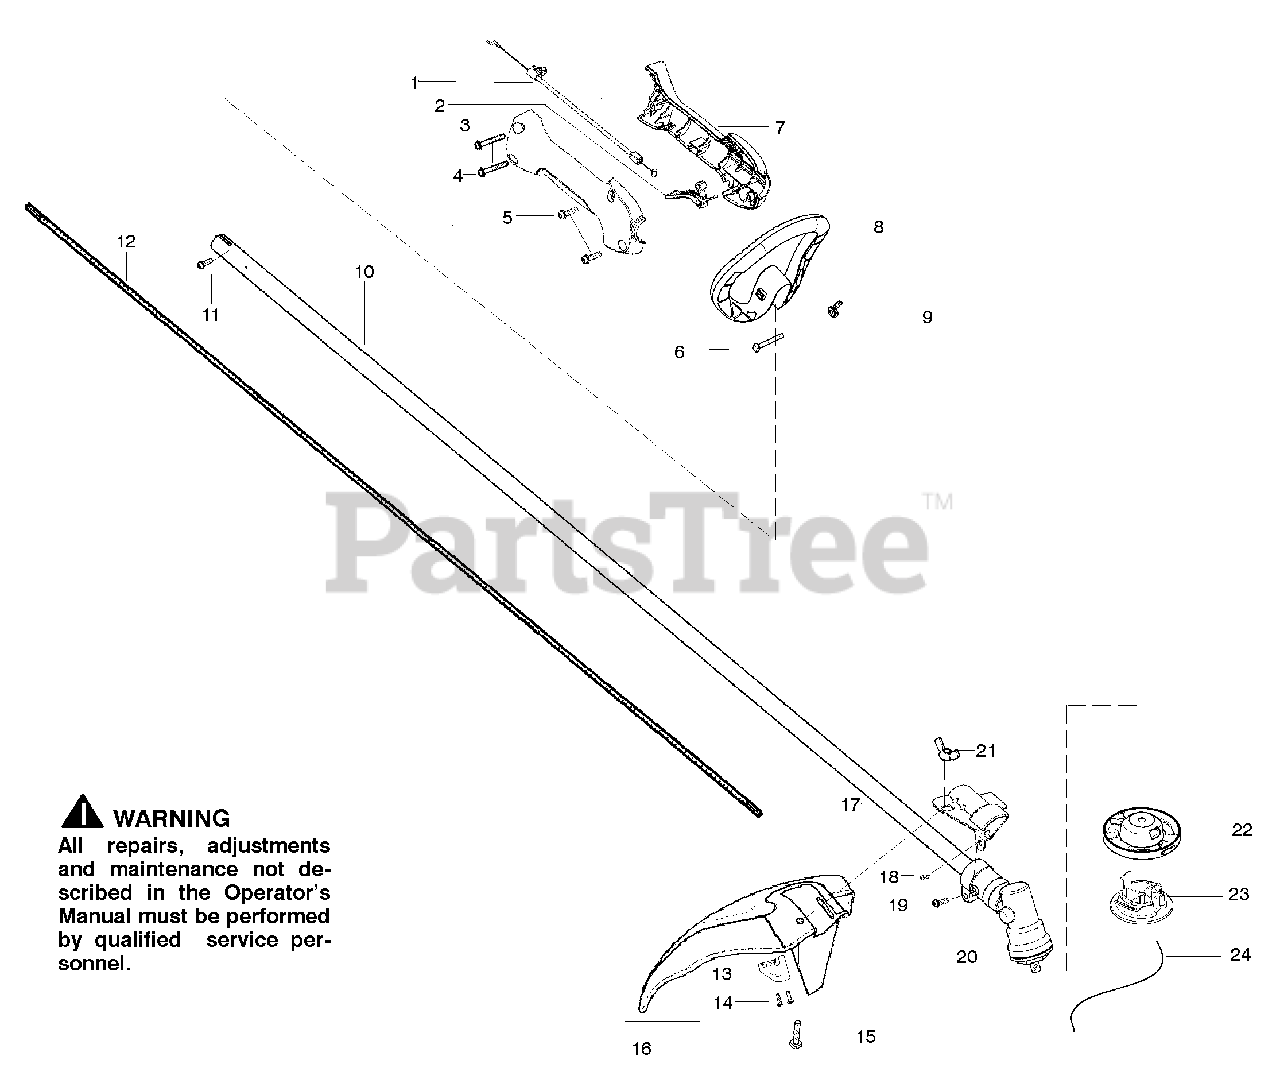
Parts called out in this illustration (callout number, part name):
1	Assy-Throttle Cable
3	Throttle Hsg. (Right)
6	Bolt-Handle
7	Throttle Hsg. (Left)
8	Assy-Handle
9	Wingnut-Handle
10	Assy-Drive Shaft Hsg.
11	Screw
12	Shaft- Flex
13	Line Limiter
15	Bolt-Shield
16	Kit-Shield Assy
17	Bracket-Shield
20	Assy-Gearbox
21	Wingnut
22	Head- Fixed Line
23	Cap- Fixed line
24	Line .095 round (5 pcs)
